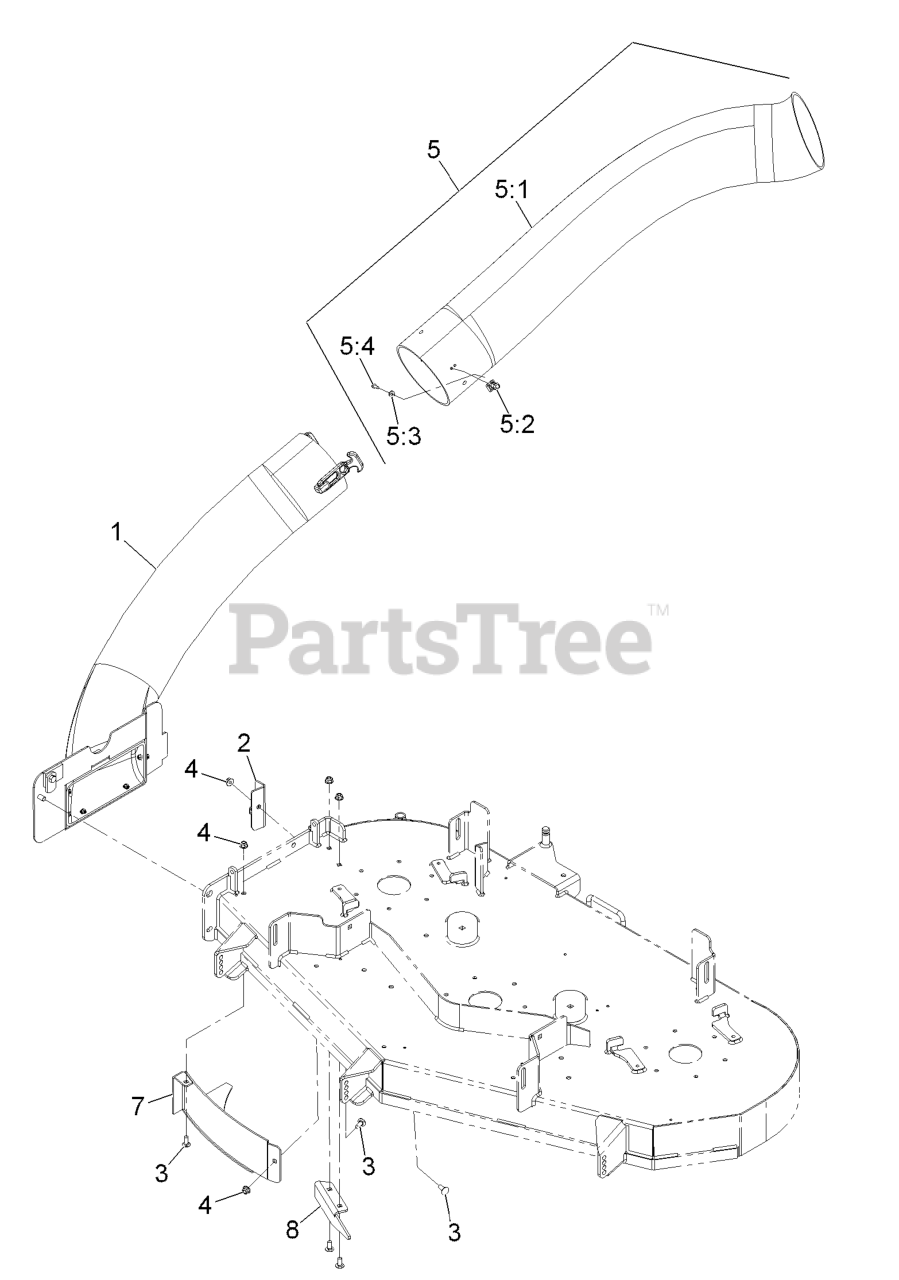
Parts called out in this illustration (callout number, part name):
1	TUBE AND FRAME ASM
2	BRACKET-BOOT MOUNT, 52 IN
2	BRACKET-BOOT MOUNT, 48 IN
3	SCREW-CARR
4	NUT-HF, NI
5	UPPER TUBE W/KEEPER ASM
5:1	TUBE-UPPER
5:2	LATCH-KEEPER
5:3	WASHER-FLAT
5:4	SCREW-PPH
7	WLD,DISCHARGE BAFFLE
8	BAFFLE-DISCHARGE
